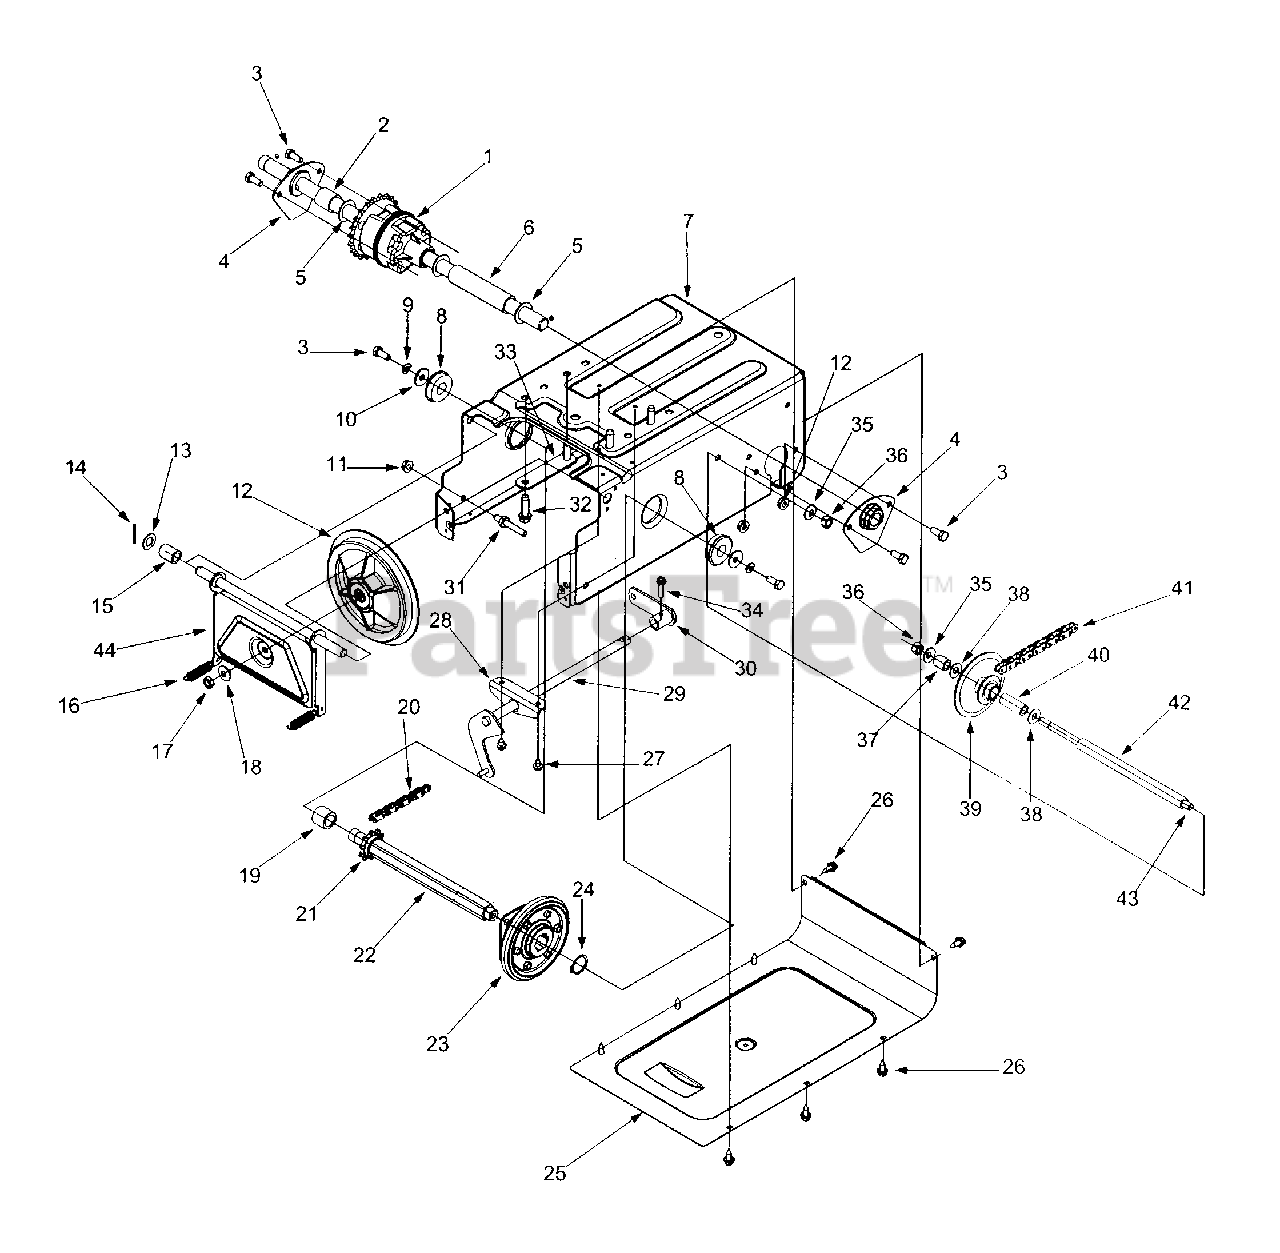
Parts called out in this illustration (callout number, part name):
1	Transmission Assembly
2	Spacer .782 ID x 1.0 OD
3	Hex Cap Screw 5/16-18 x .75
4	Axle Bracket Assembly
5	Flat Washer .793 ID x 1.24 OD
6	Spacer .782 ID x 1.0 OD
9	Lock Washer 5/16
10	Flat Washer .312 ID x .934 OD
11	Flange Lock Nut 5/16-18
12	Friction Disc Assembly
13	Flat Washer .53 ID x .93 OD
14	Cotter Pin
15	Spacer .508 ID x .75 OD
16	Extension Spring .48 OD x 2.03
17	Jam Nut 3/8-24
18	Spring Washer .401 ID x .870 OD
19	Spacer .675 ID x 1.0 OD
20	Chain #41 36 Links
21	Sprocket 10T #41
22	Hex Shaft .875
23	Friction Wheel Assembly
24	Snap Ring 1.0 Dia.
27	Hex Washer Screw 1/4-20 x .375
29	Shift Shaft Assembly
32	Hex Washer Screw 3/8-16 x 1.25
35	Spring Washer .401 ID x .870 OD
36	Hex Nut 3/8-24
37	Spacer .407 ID x .625 OD
38	Flat Washer .375 ID x .870 OD
39	Sprocket Assembly 9T & 22T
40	Sleeve .380 ID x .623 OD x 1.5
41	Chain #420 36L
42	Spacer .407 ID x .625 OD x 7.86
43	Jack Shaft .375 x 11.40
44	Friction Wheel Support Bracket
